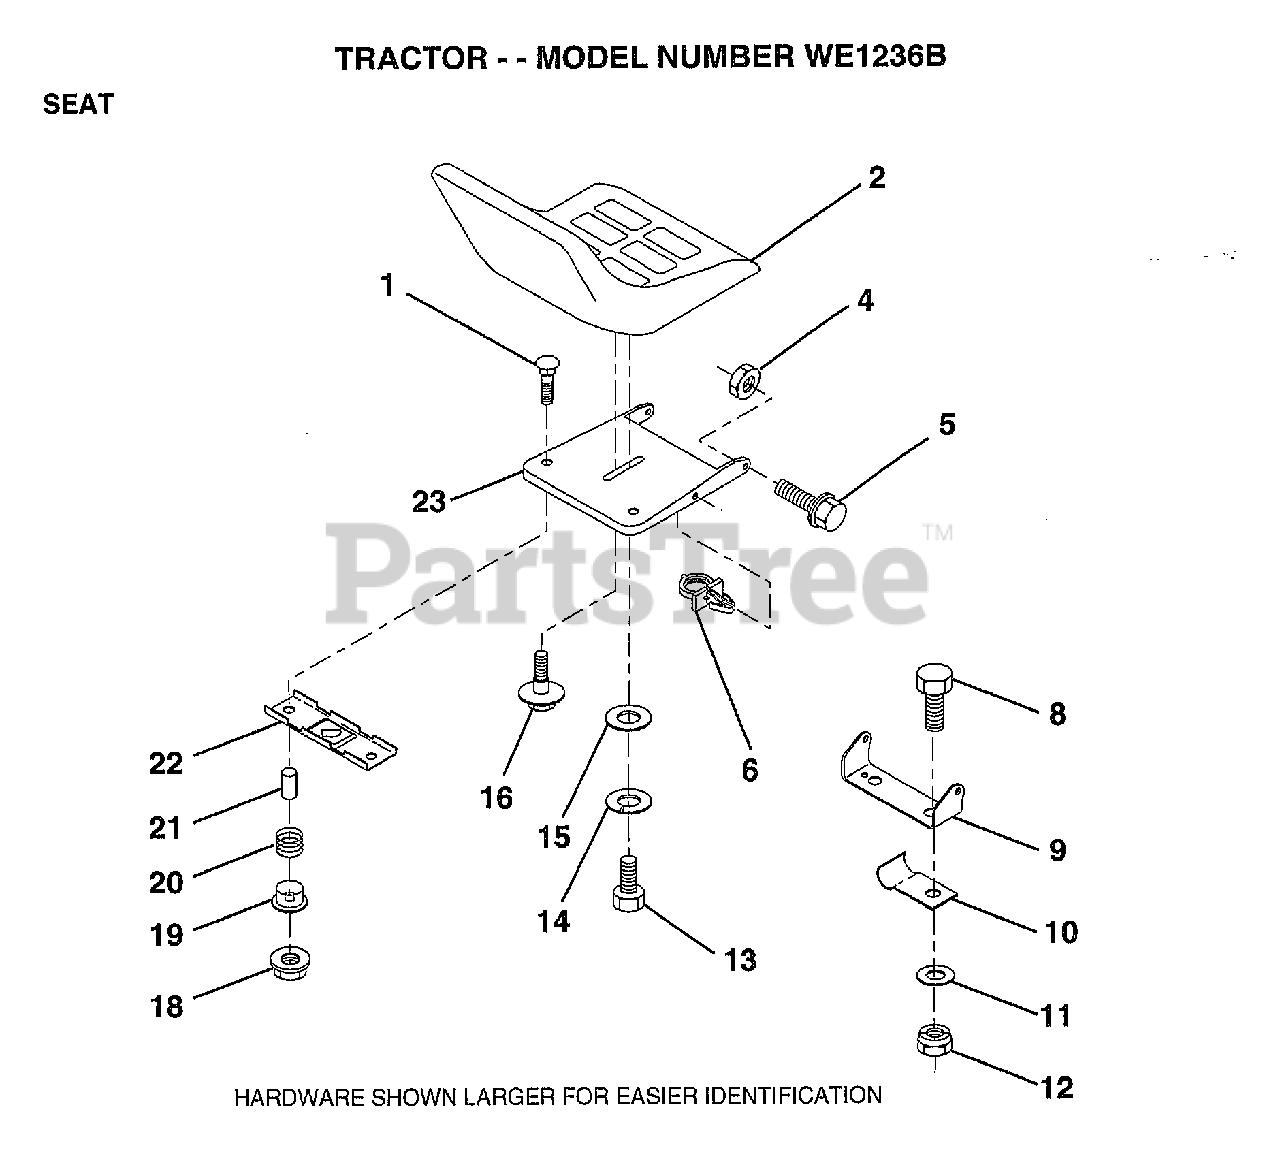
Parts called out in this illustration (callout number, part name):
4	NUT
5	BOLT.SHLD.5/16-18
6	CLIP.PUSH-IN.HING
8	BOLT
9	BRACKET PVT SEAT
10	"CLIP,INSULATOR"
11	WASHER
12	NUT
13	BOLT
14	LOCKWASHER
15	WASHER
16	"BOLT,SHOULDER"
19	BUSHING
20	SPRING
21	SPLIT SPACER
22	BRKT SWITCH
